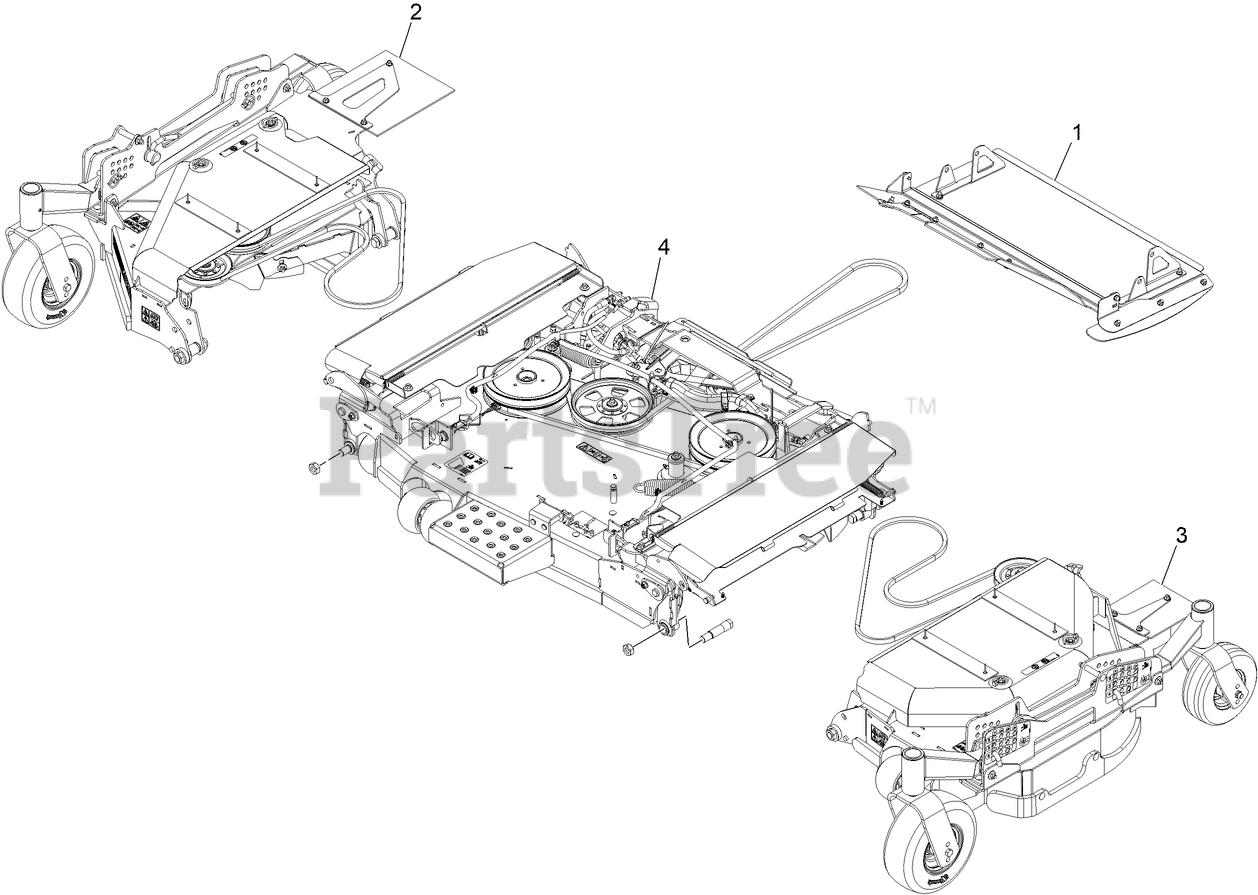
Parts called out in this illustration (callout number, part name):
1	Discharge-Tunnel ASM, 96-Gas
2	ASM-Deck, RH Wing [gas]
2	ASM-Deck, RH Wing Gas 96E
3	ASM-Deck, LH Wing [gas]
3	ASM-Deck, LH Wing Gas 96E
4	ASM-Deck, Ctr Gas 96E
